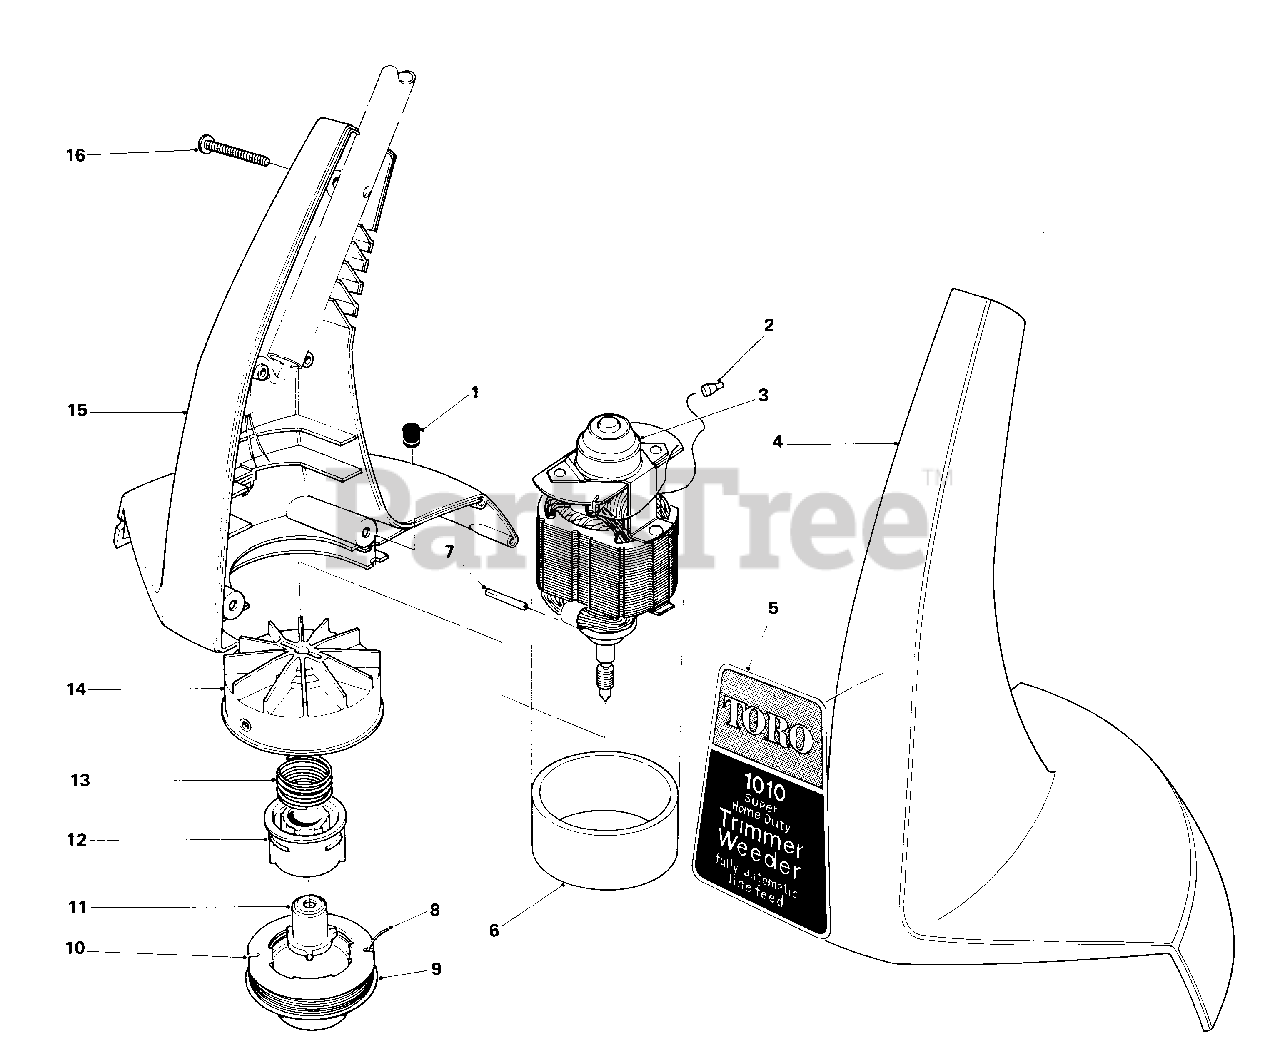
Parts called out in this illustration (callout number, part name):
2	Electrical Connector
4	Housing, L.H.
5	Decal-Housing
6	Dampening Sleeve
8	Filament Line 30'(.050 Dia.)
9	Spool Cap
10	Prewound Spool Cap
11	Driver-Detent
12	Spool Core
13	Spring-Compression
14	Fan Hub Assembly
15	Housing Assembly, R.H.
16	Cross Recess Pan Hd. Thread Forming Screw
